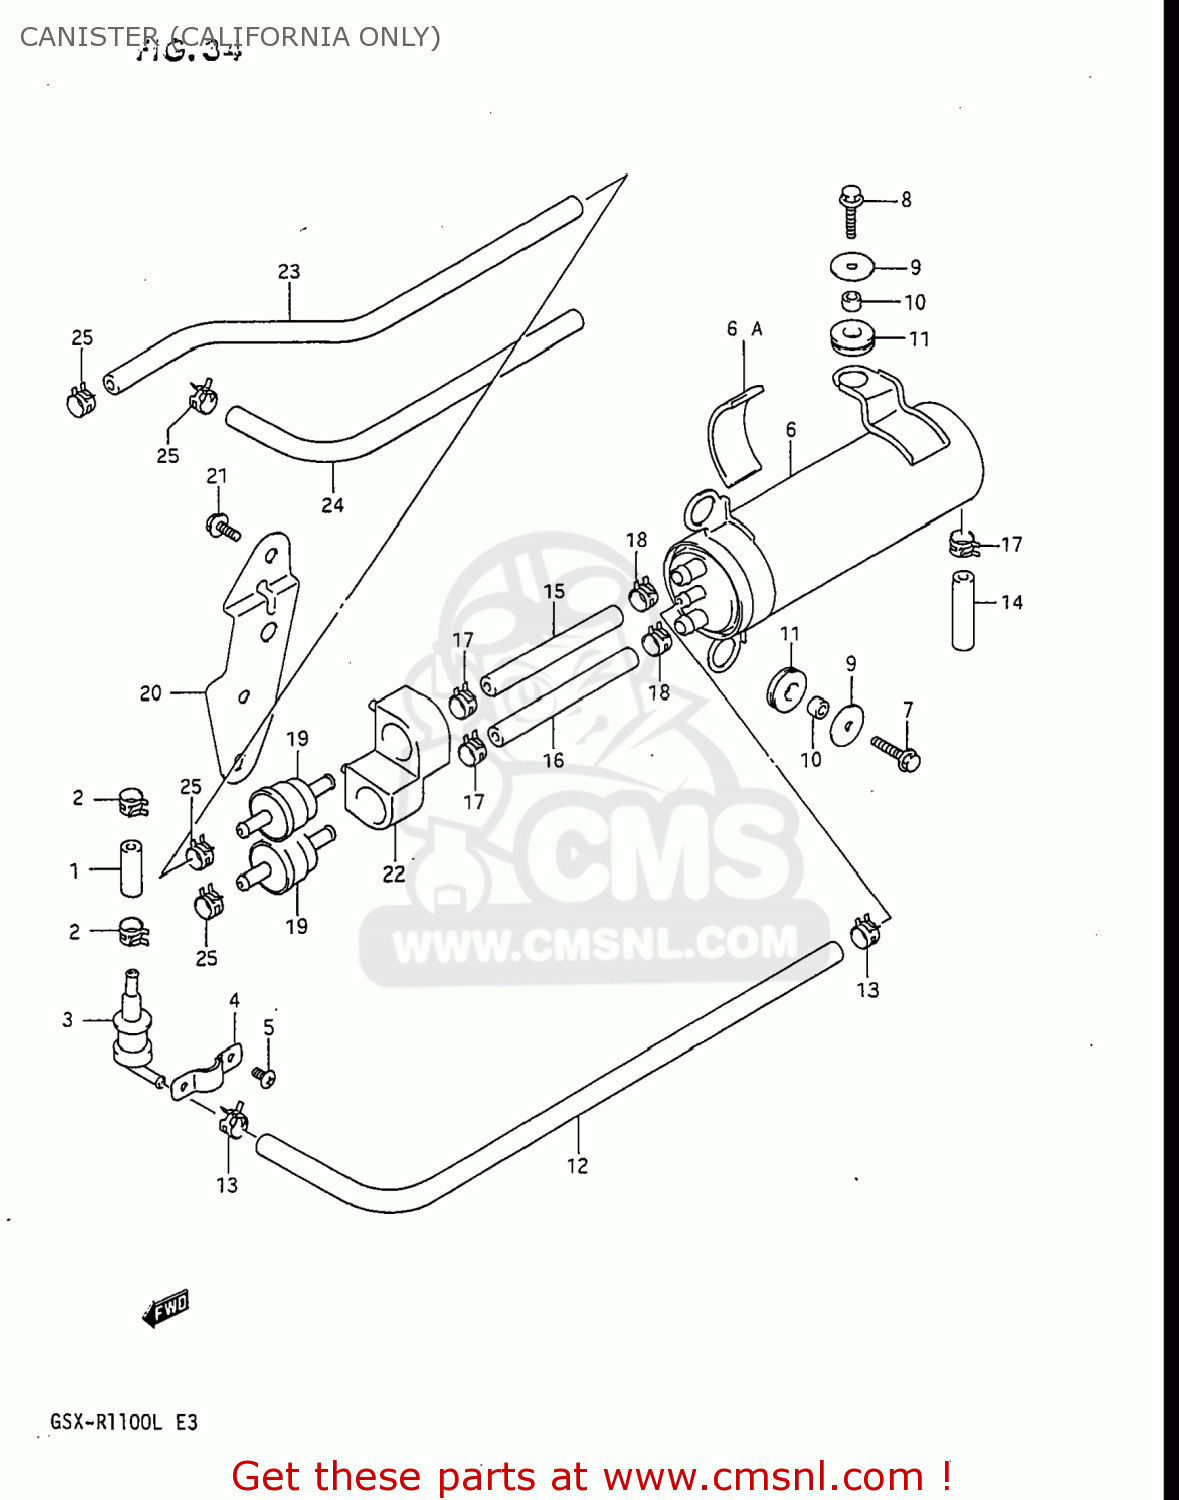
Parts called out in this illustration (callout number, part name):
1	HOSE
2	(CA) CLIP
3	VALVE,FUEL TANK BREATHER
4	PLATE,FUEL TANK BREATHER NO.2
5	SCREW
6	(CA) CANISTER COMP,CHARCOAL
6A	(CA) CUSHION,CANISTER
7	BOLT
8	BOLT
9	WASHER (6.5X24X1.6)
10	SPACER(6.5X10.5X6.5)
11	CUSHION
12	HOSE
13	(CA) CLIP
14	HOSE
15	HOSE
16	HOSE
17	(CA) CLIP
18	CLAMP
19	VALVE,CANISTER PURGE
20	BRACKET,CANISTER
21	BOLT
22	(CA) CUSHION,CANISTER P VA
23	HOSE
24	HOSE
25	(CA) CLIP
